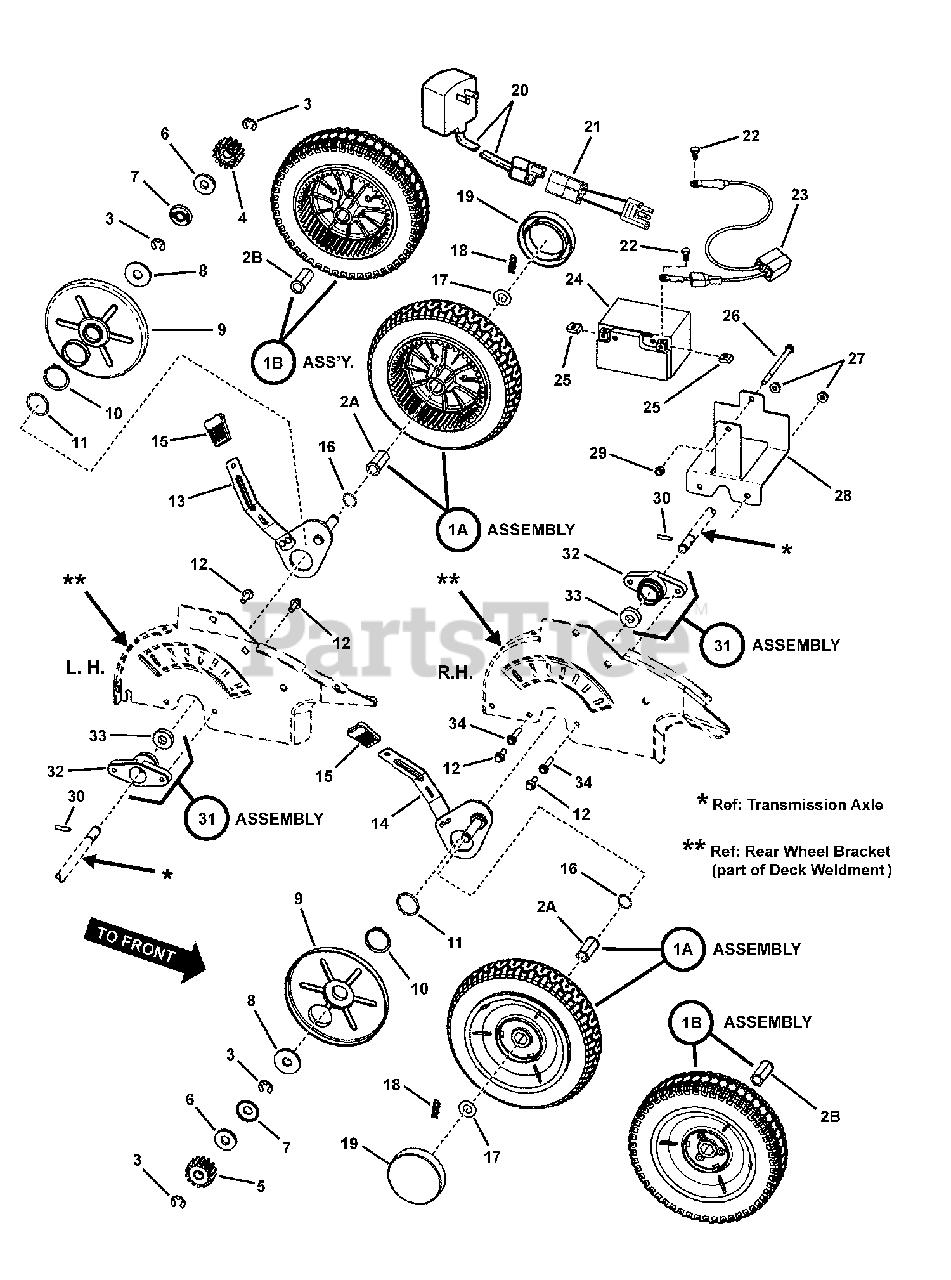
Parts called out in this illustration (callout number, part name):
1A	ASSEMBLY, 9" x 2" Gear Wheel, LS Tread
1B	ASSEMBLY, 9" x 2" Gear Wheel, Double Bar II Tread
2A	BUSHING, Wheel (powdered metal)
2B	BUSHING, Wheel (nylon)
3	RETAINING RING
4	PINION, LH Drive
5	PINION, RH Drive
6	SEAL, Pinion (Felt)
7	RETAINER, Pinion Seal
8	WASHER, .531 x 1.25 x .06 thick
9	SHIELD, Dust
10	SNAP RING, 1-3/8"
11	O-RING, Buna N, 124
12	BOLT, 1/4-20 x 3/4" Hex Flange Lock
13	ASSEMBLY, Axle Arm, Left Rear
14	ASSEMBLY, Axle Arm, Right Rear
15	GRIP, Height Latch - Black (1.3" Wide)
16	O-RING, Buna N, 018
17	WASHER, 1/2" Flat
18	COTTER, Hairpin
19	HUB CAP, 3-1/4" Diameter (black)
20	* CHARGER, Battery 120V/12V
21	* ADAPTER, Charger
22	* SCREW, #10-24 x 1/2" Pan Head Machine
23	* WIRING HARNESS, Battery
24	* BATTERY, 12V Sealed Lead Acid
25	* NUT, #10-24 Square
26	* SCREW 1/4-20 x 4" Hex Head Cap, GR 5
27	* NUT, 1/4-20 Hex Flange Lock
28	* BRACKET, Battery
29	* NUT, 1/4-20 Hex Nyloc
30	PAWL, 3/16" O.D.
31	ASSEMBLY, Axle Bearing
32	HOUSING, Axle Bearing
33	BALL BEARING, Axle
34	* SCREW, 1/4-20 x 1-1/2" Hex Washer Self Tap
